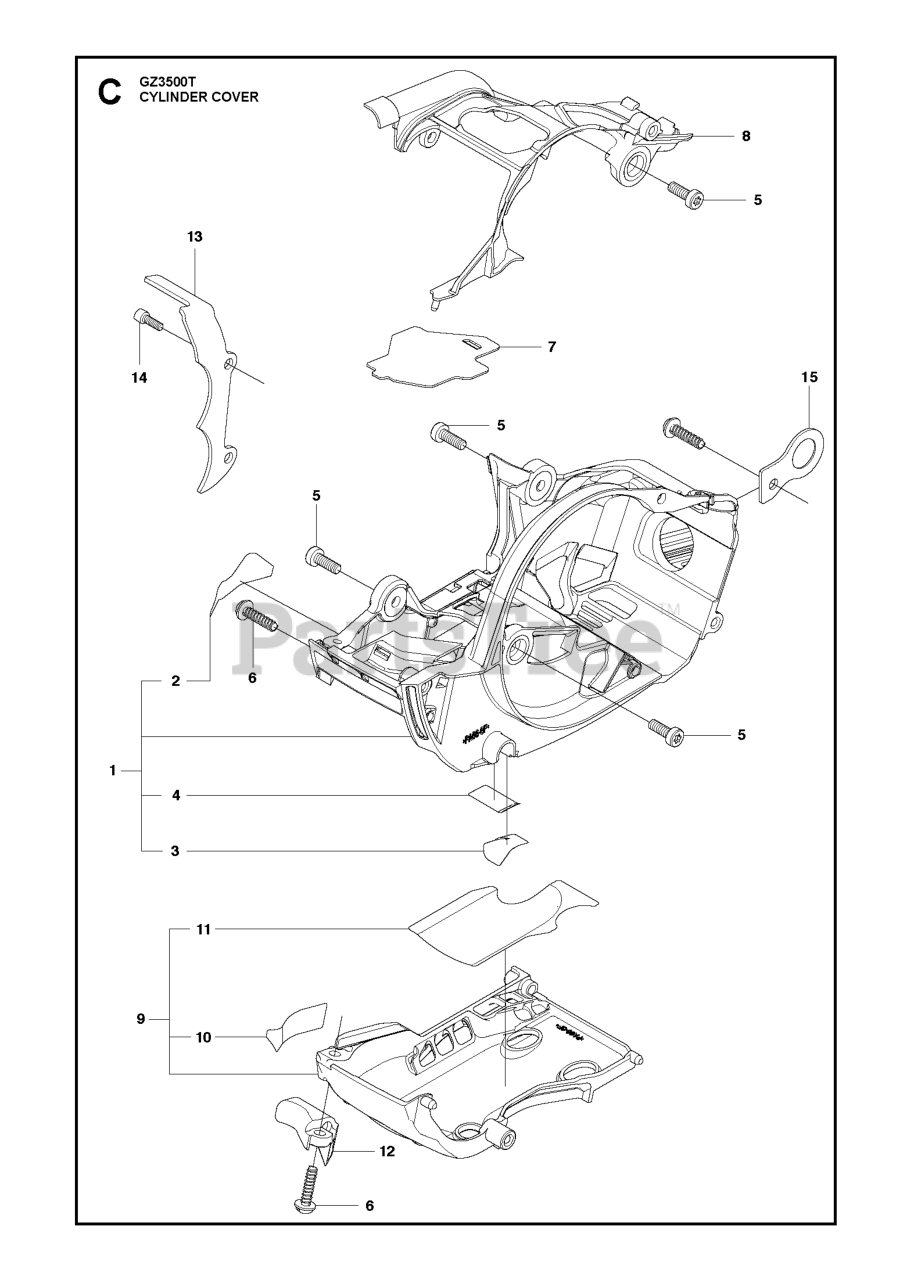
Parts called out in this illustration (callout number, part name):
1	CASE-COMP
2	TAPE, CASE
3	TAPE, CASE
4	TAPE, CASE
6	SCREW (RPLS 267132210)
8	COVER TOP
9	CASE, ASSY
12	CATCHER (RPLS -66F1)
13	SPIKE 439
